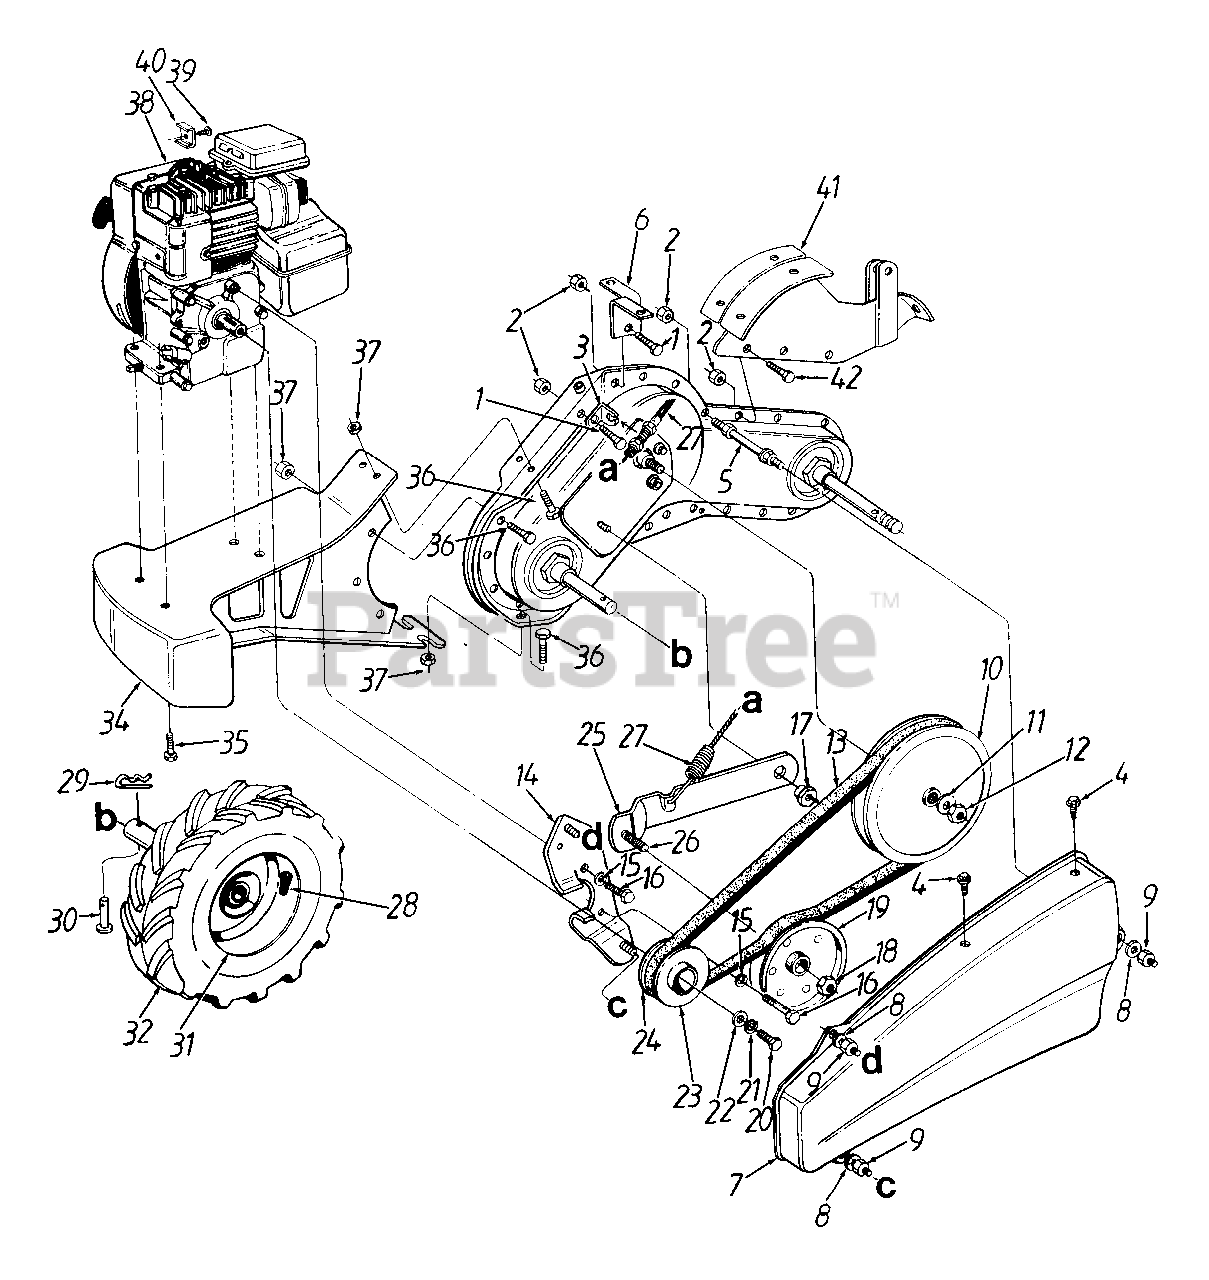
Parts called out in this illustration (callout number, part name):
1	Hex Bolt 5/16-18 x .75" Lg.
2	Hex Flange Top L-Nut 5/16-18 Thd.
3	Cable Mtg. Bracket
4	Torx Mach. AB-Tap Scr. 1/4 x .6" Lg.
5	Belt Cover Bolt
9	Hex Cap Nut 1/4-28 Thd.
10	Flat Pulley 8" O.D.
11	Bell-Wash. .38" I.D. x .88" O.D.
12	Hex Ins. L-Nut 3/8-16 Thd.
13	"V"-Belt
16	Hex Bolt 5/16-24 x .62" Lg.
17	Shld. Nut
18	Hex Jam L-Nut 3/8-16 Thd.
19	Fl-Idler w/Flanges
20	Hex Bolt 3/8-24 x 1" Lg.
21	L-Wash. 3/8" I.D.
22	Fl-Wash. 3/8" I.D. x 1" O.D.
23	Outer Engine Pulley Half
24	Inner Engine Pulley Half
26	Hex Cap Bolt 3/8-16 x 1.25" Lg.
27	Clutch Cable
28	Air Valve
29	Hairpin Clip
30	Clevis Pin
34	Frame Counterweight
35	Hex L-Wash. TT-Tap Scr. 3/8-16 Thd.
36	Hex Cap Bolt 5/16-18 x 1" Lg. (Gr. 5)
37	Hex Flange L-Nut 5/16-18 Thd.
38	Engine
39	Hex Sems Scr. #10-32 x .62" Lg.
40	Casing Clamp
